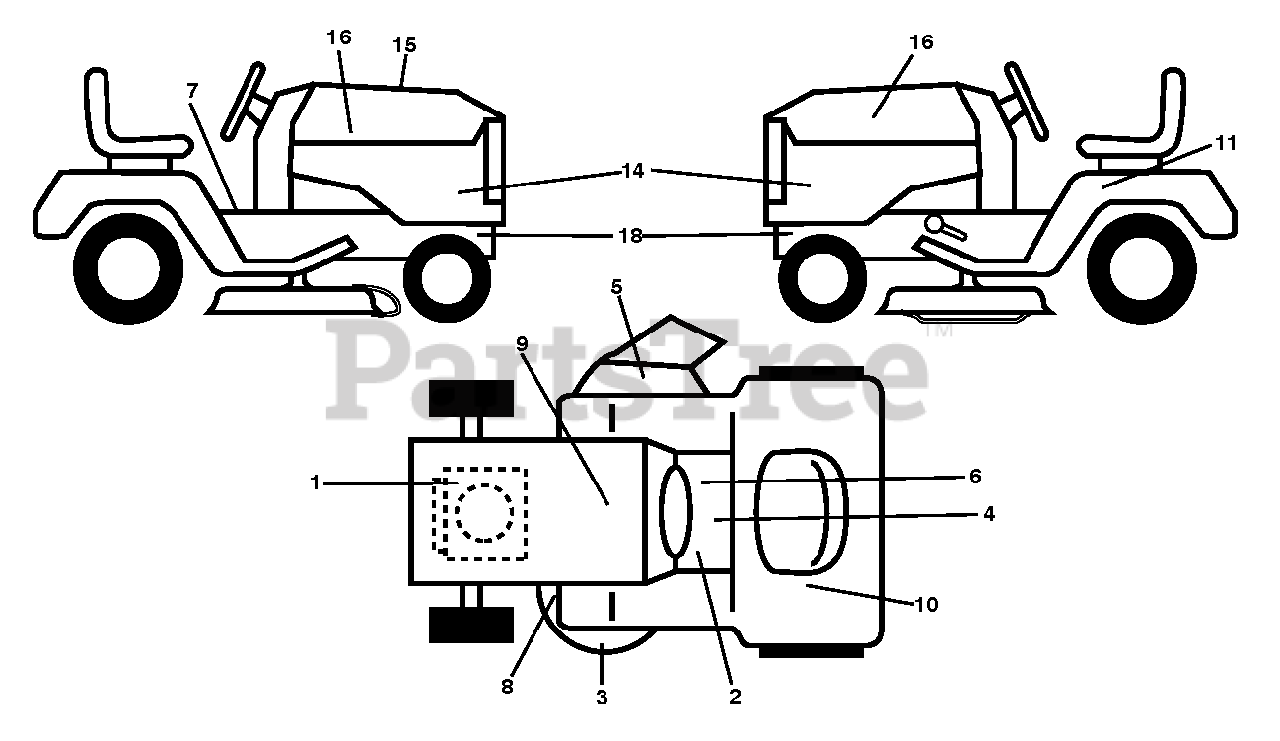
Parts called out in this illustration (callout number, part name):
1	DECAL.ENGINE.WARNING
2	DECAL.FNDR.SDLE.BRAKE.CLUTCH.6
3	DECAL.DECK.CLEARCUT.NOSTEP
4	DECAL.FWD/REV.PEDAL.SYMBOL
5	Decal, TRACTZTR DECKWA
6	DECAL.PARKING.BRAKE.SADDLE.LT
7	DECAL.READ.OWN.MAN.SYMBOL.LT
8	DECAL.V-BELT.SCH.42/46"MEC/ELE
9	DECAL BTRY SYMBOLS
10	DECAL.RESERVEFUELSELCTR.ENG
11	DECAL CERTIFICATION DECAL EMCC
14	DECAL.SDPNL.TS342.SET
15	Decal, Replacement Kawasaki FR TLB
16	DECAL.BADGE.170MM.TEXTLOGO.
18	DECAL.CHASSIS.HOT.MUFFLER
